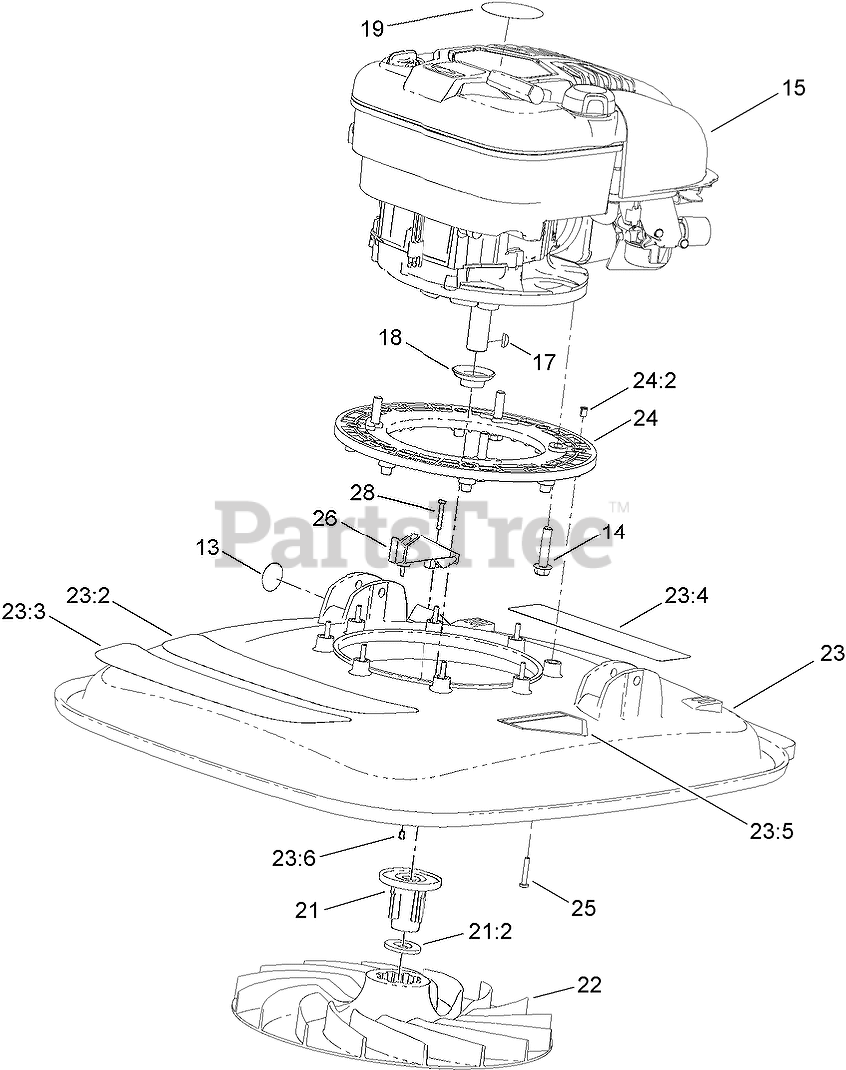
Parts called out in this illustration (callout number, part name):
13	DECAL
14	SCREW-TAPTITE
15	ENGINE-Honda
17	KEY-WOODRUFF
18	PROTECTOR-SEAL, OIL
19	DECAL-ENGINE
21	DRIVE AND SPACER ASM
21:2	WASHER-PLAIN
22	IMPELLER
23	DECK ASM
23:2	DECAL-HOVER PRO, 500 SERIES
23:3	DECAL-HOVER PRO, 550 SERIES
23:4	DECAL-WARNING
23:5	DECAL-DANGER
23:6	INSERT
24	FRAME-ENGINE
24:2	INSERT-BRASS
25	SET-SCREW
26	BRACKET
28	SCREW
